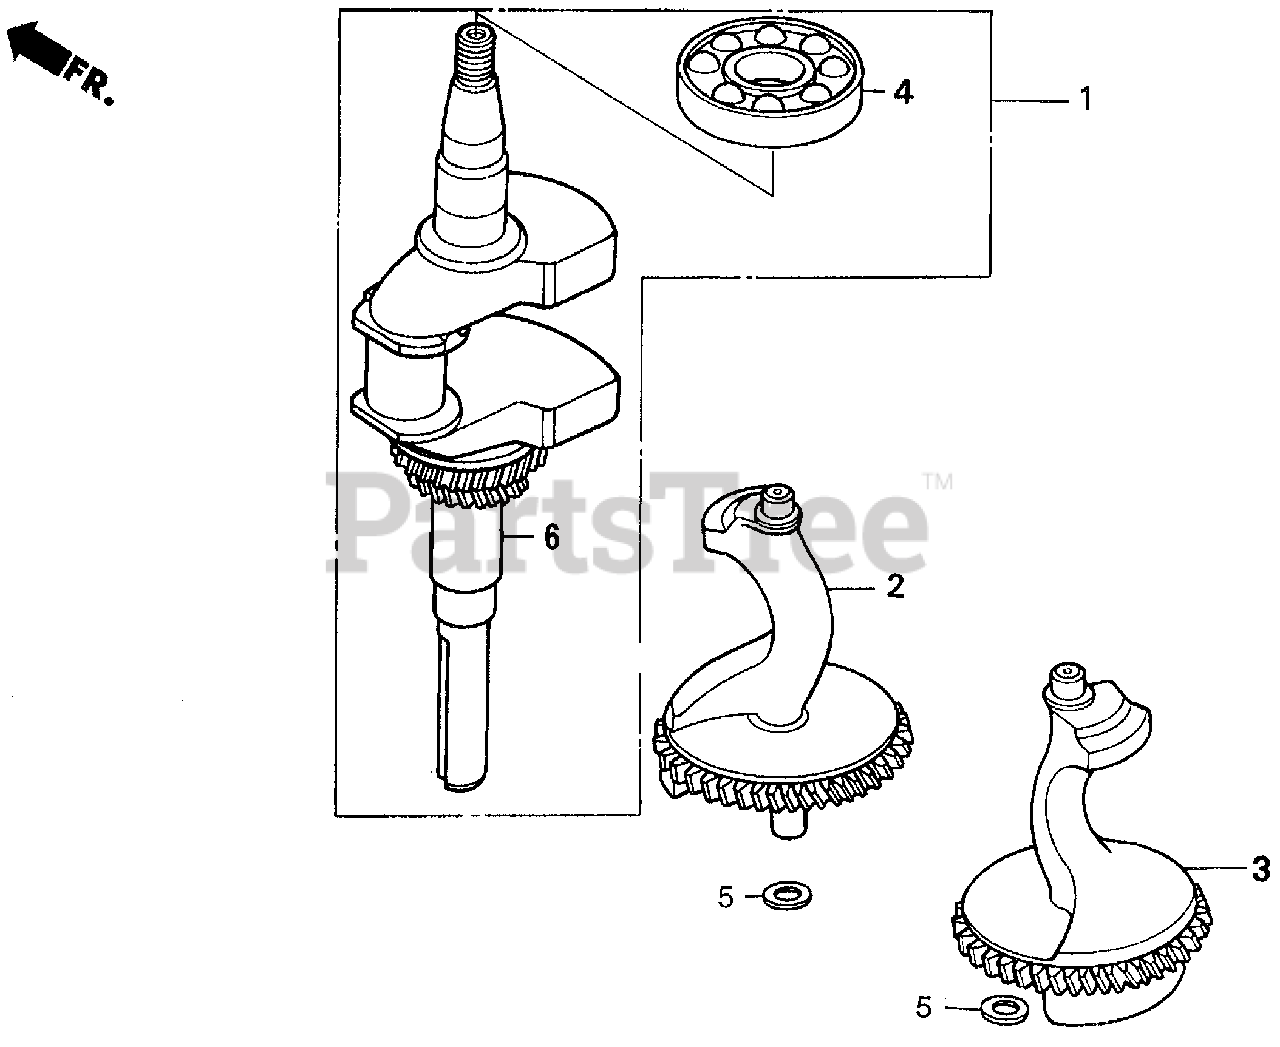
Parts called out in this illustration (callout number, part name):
1	CRANKSHAFT
2	WEIGHT A, BALANCER
3	WEIGHT B, BALANCER
4	BEARING, RADIAL BALL (6207)
5	CRANKSHAFT
5	WASHER, THRUST (14MM)
